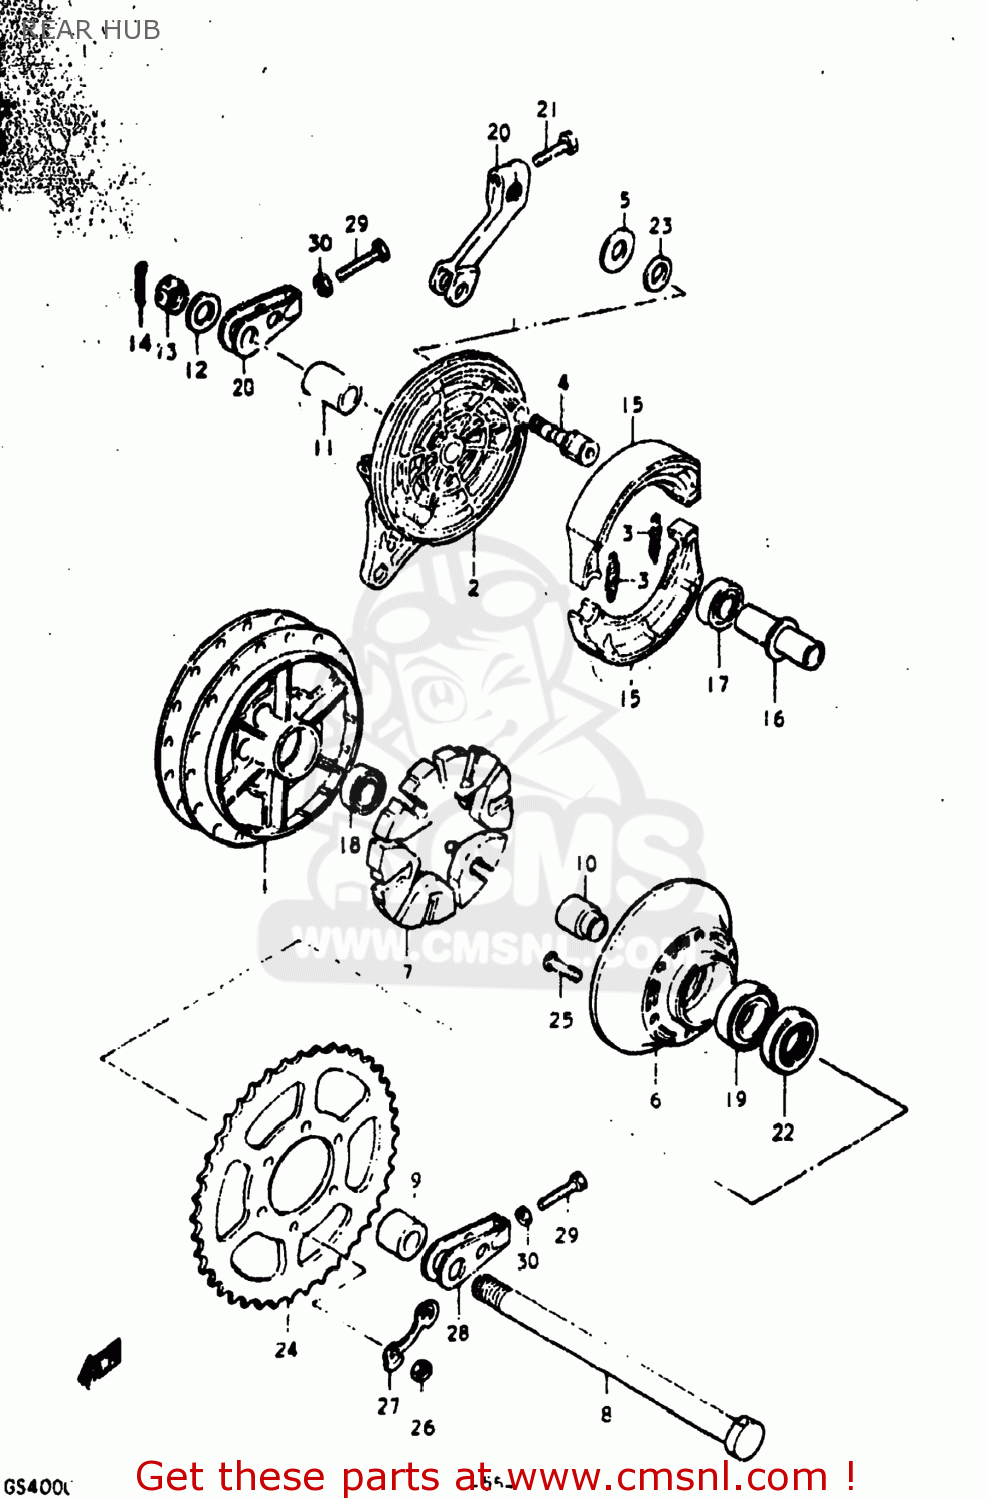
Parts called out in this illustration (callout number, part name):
1	DRUM,REAR HUB
2	PANEL,REAR HUB
3	SPRING,BRAKE SHOE
4	CAM,FRONT BRAKE
5	WASHER (15X24X1.6)
6	DRUM,REAR SPROCKET MOUNT
7	CUSHION,REAR DRUM
8	AXLE,REAR
9	SPACER(17X30.5X22.3)
10	SPACER,REAR HUB BEARING
11	SPACER(17X30.5X22.3)
12	WASHER
13	NUT
14	PIN, COTTER
15	SHOE SET,BRAKE (MCA)
16	SPACER
17	BALL BEARING
18	BEARING
19	BEARING
20	LEVER,REAR BRAKE CAM
21	BOLT
22	OIL SEAL
23	O-RING,BOSS
24	SPROCKET,RR
25	BOLT
26	NUT
27	WASHER
28	ADJUSTER,CHAIN
29	BOLT
30	NUT
